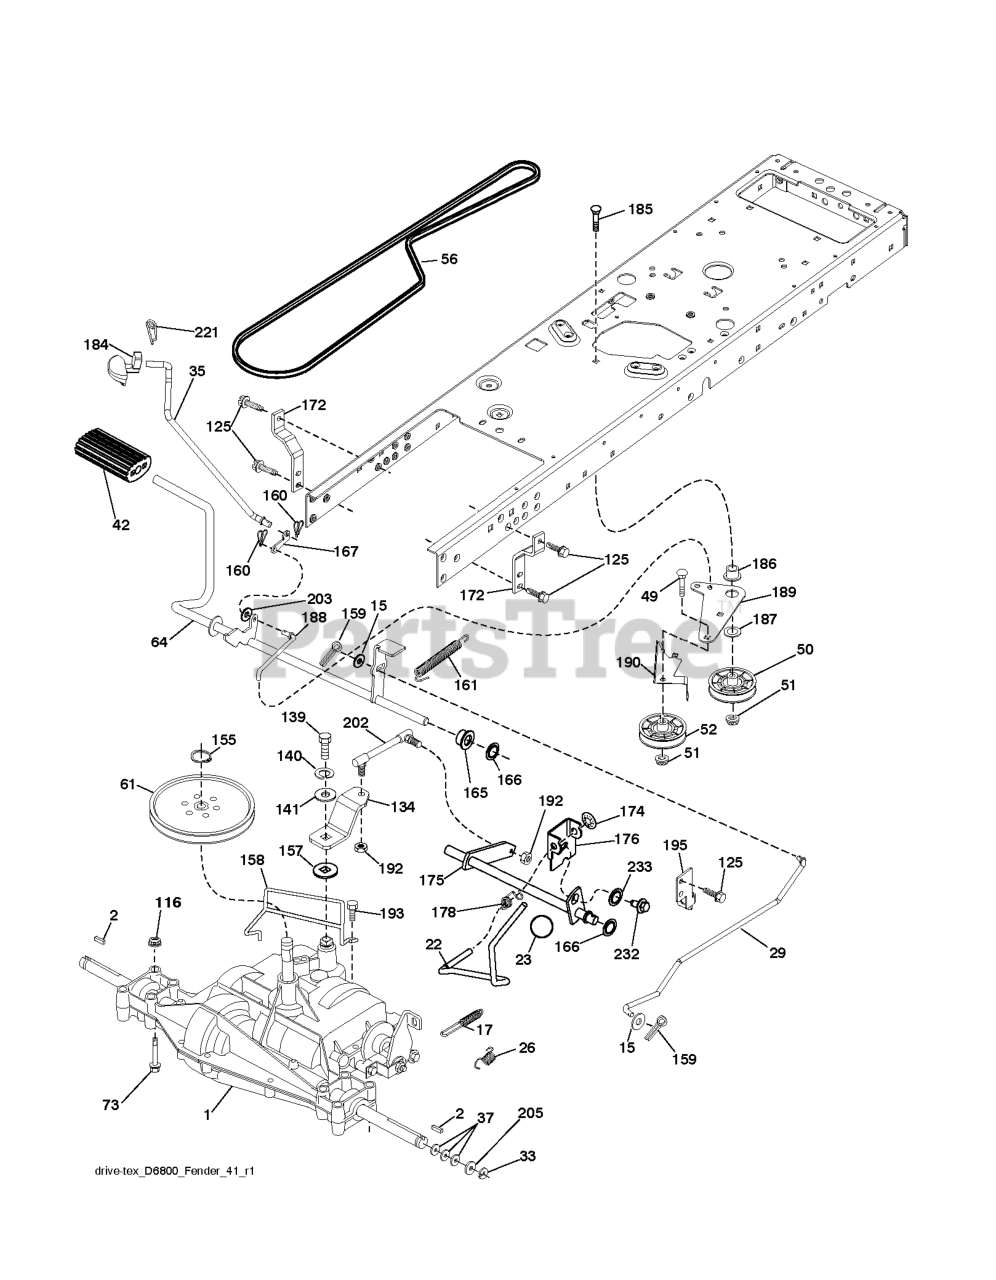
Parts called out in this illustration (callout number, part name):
2	SQUARE KEY
15	WASHER
17	SPRING.BRAKE.PEERLESS.TEX
22	ROD.SHIFT.FENDER.TLT.2006
23	KNOB.DUCKHEAD.1/2
26	SPRING.BRAKE.RTN.GR.DR
29	ROD.BRAKE.PEERLESS
35	ROD.CNTRL.PARK.PREDATOR.LT.TEX
42	PEDAL COVER T
50	IDLER.FLAT.910.OFFSET
51	NUT LOCK FLG 3/8-16 UNC
52	IDLER.V-GROOVE.910.OFFSET
61	PULLEY TRANS
64	SHAFT.ASM.PEDAL.BRAKE.
73	BOLT HEX 5/16-18 GR 5
116	NUT LOCK HEX FLANGE 5/16-18
125	SCREW
134	ARM.SHIFT.
139	BOLT 1/4-28X3/4
140	LOCKWASHER
155	RETAINING RING LT
157	WASH-SHFT PLT LT
158	KEEPER.PMS.18/20.D4365
159	COTTER PIN
160	RETAINER CLIP
161	SPRING, RETURN LT
165	BUSHING.SHAFT.BRAKE.HAND
166	NUT.PUSH.625
167	LATCH.BRAKE.SPRING
172	STRAP.TRQ.LH.GEAR.DRIV
174	NUT.PUSH.500.2006
175	SHAFT.ASM.SHIFT.
176	ARM.CLEVIS.ROD.SHIFT
178	SPRING.SHIFT.GT2006
184	HANDLE PARKING BRAKE
186	SPACER.RETAINER
187	WASHER 12/32X2X10GA
188	RP.LINK.CLUTCH.GROUND.DRIVE
189	BELLCRANK.GROUND.DRIVE.TEX.
190	KEEPER.BELLCRANK.DRIVE
192	NUT LOCK CENTER 1/4 -28 FNTHD
193	SCREW 5/16"
195	BRKT.ROD.BRAKE.PEERLES
202	LINK.TRANSAXLE.D6800.18/20"TEX
203	WASHER
221	RETAINER.SPRING.CLIP.H
232	BOLT FIN HEX 7/16-14 X 1
233	WASHER SERRATED
